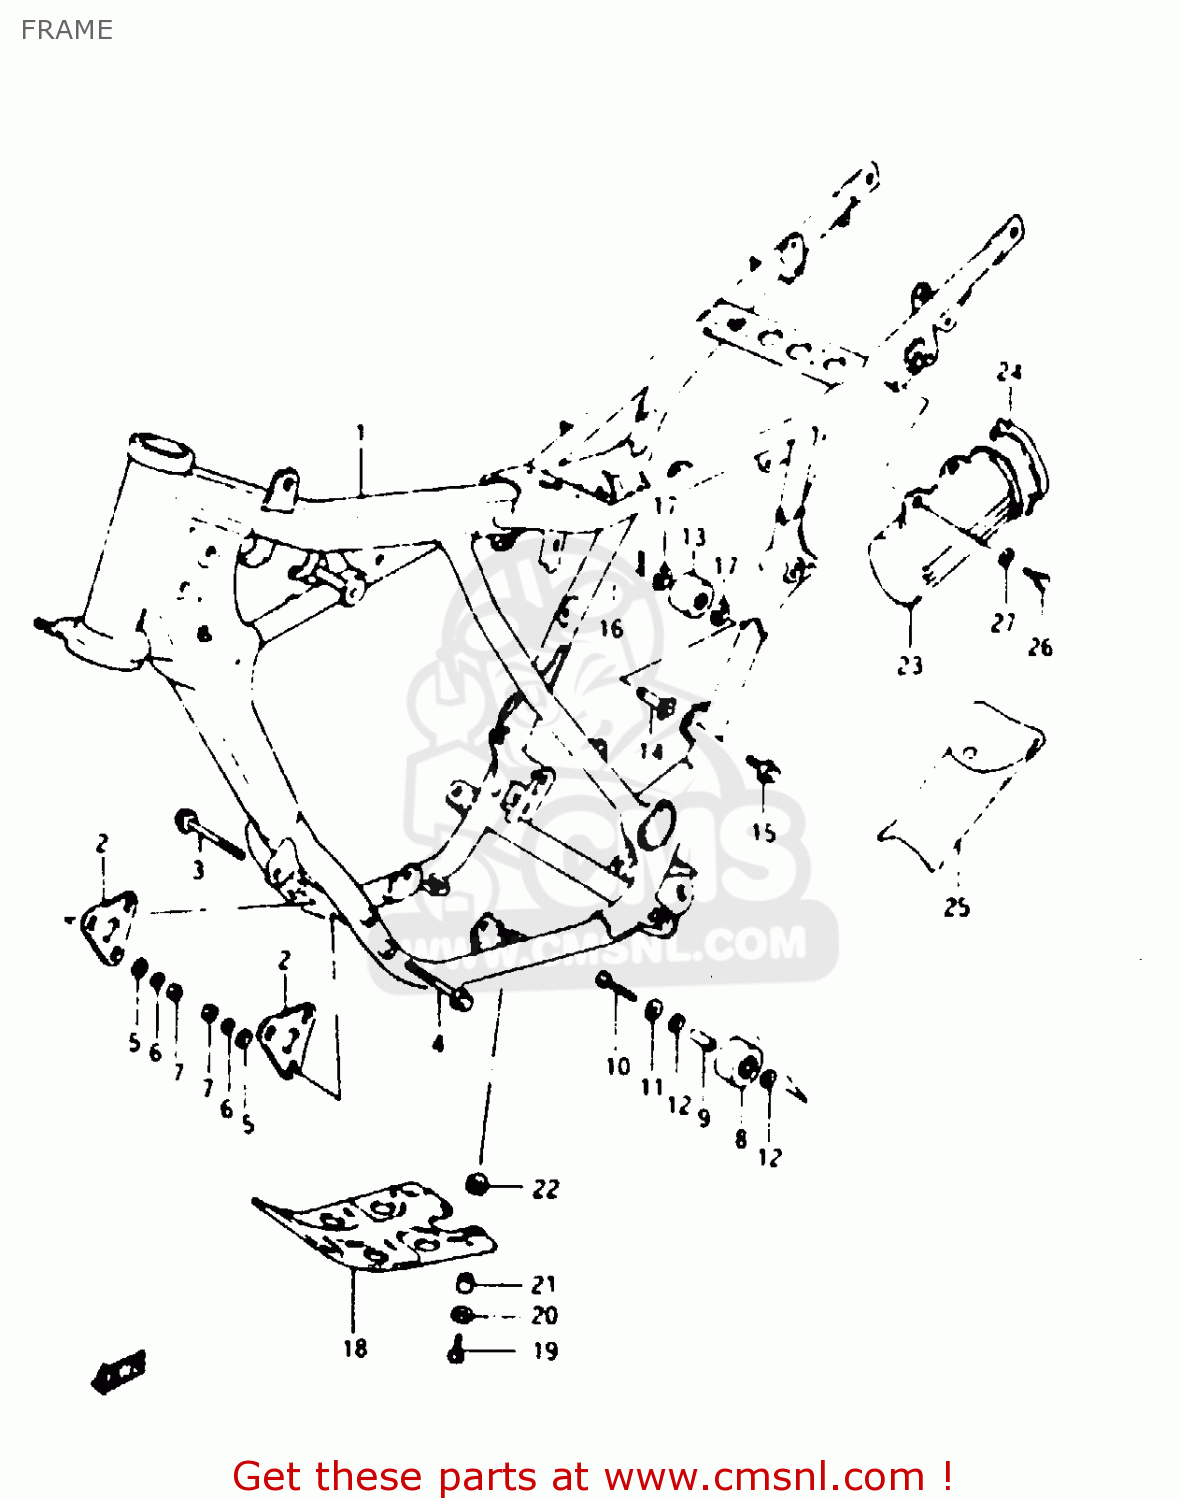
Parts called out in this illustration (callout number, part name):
1	FRAME (BLUE)
2	PLATE, ENGINE MOUNTING
3	BOLT 8X55
4	BOLT
5	WASHER
6	LOCK WASHER
7	NUT
8	ROLLER,CHAIN
9	SPACER
10	BOLT
11	WASHER
12	WASHER
13	ROLLER,CHAIN LENGTH CONTROLLER
14	BOSS,CHAIN CONTROL
15	BOLT
16	PIN 25X20
17	WASHER
18	PROTECTOR, ENGINE
19	SCREW
20	WASHER
21	SPACER(6.1X9X7.5)
22	CUSHION
23	HOLDER,TOOL
24	CAP,HOLDER
25	TOOL SET
26	BOLT 6X16
27	WASHER (6.5X18X1.6)
